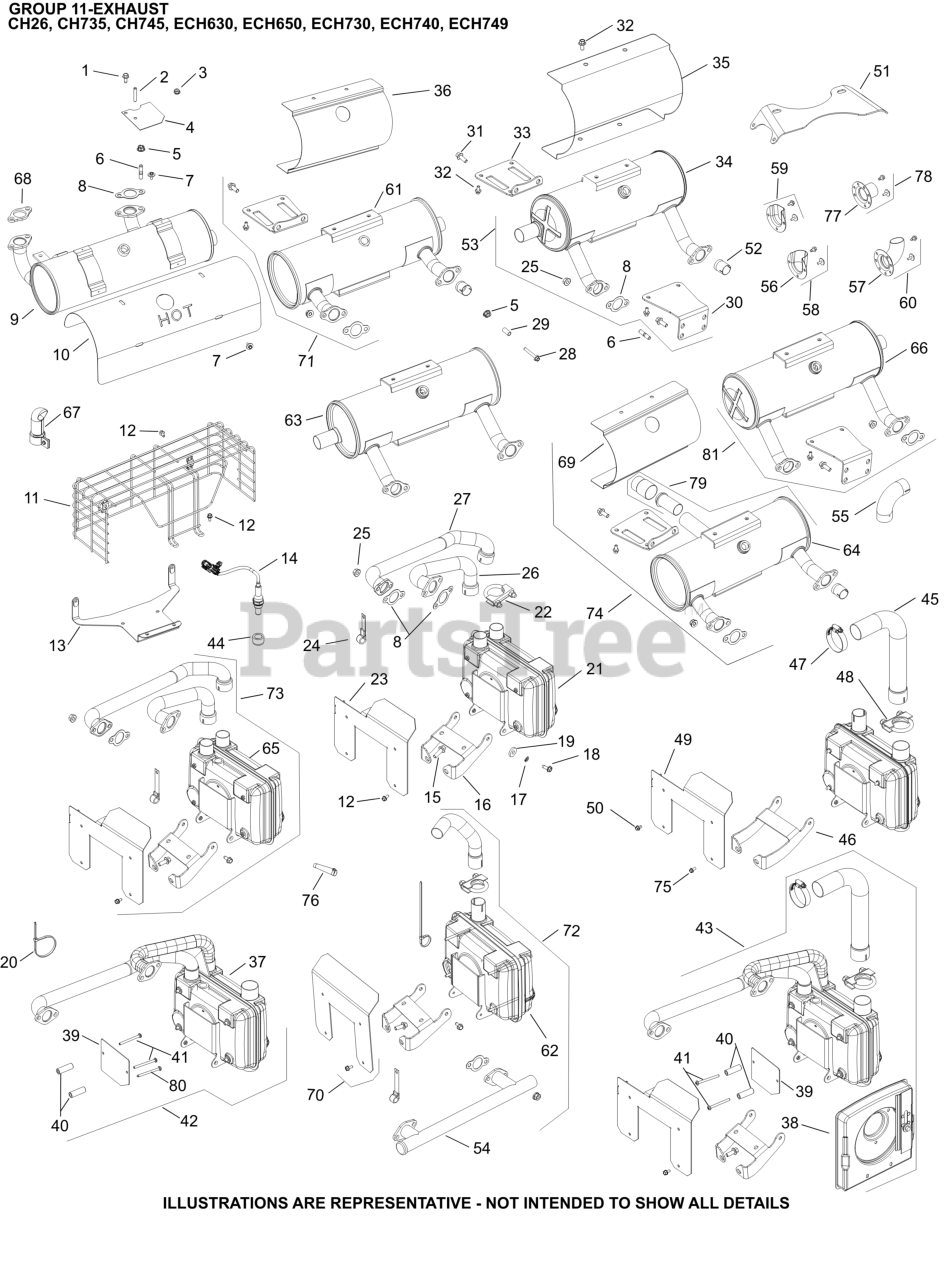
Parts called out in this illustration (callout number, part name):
5	NUT, HEX FLANGE LOCK (M8)
6	STUD, METRIC EXHAUST
8	GASKET, EXHAUST
40	SPACER, ECU GUARD
52	LINER, EXHAUST PORT
80	SCREW, HEX WASHER HEAD
